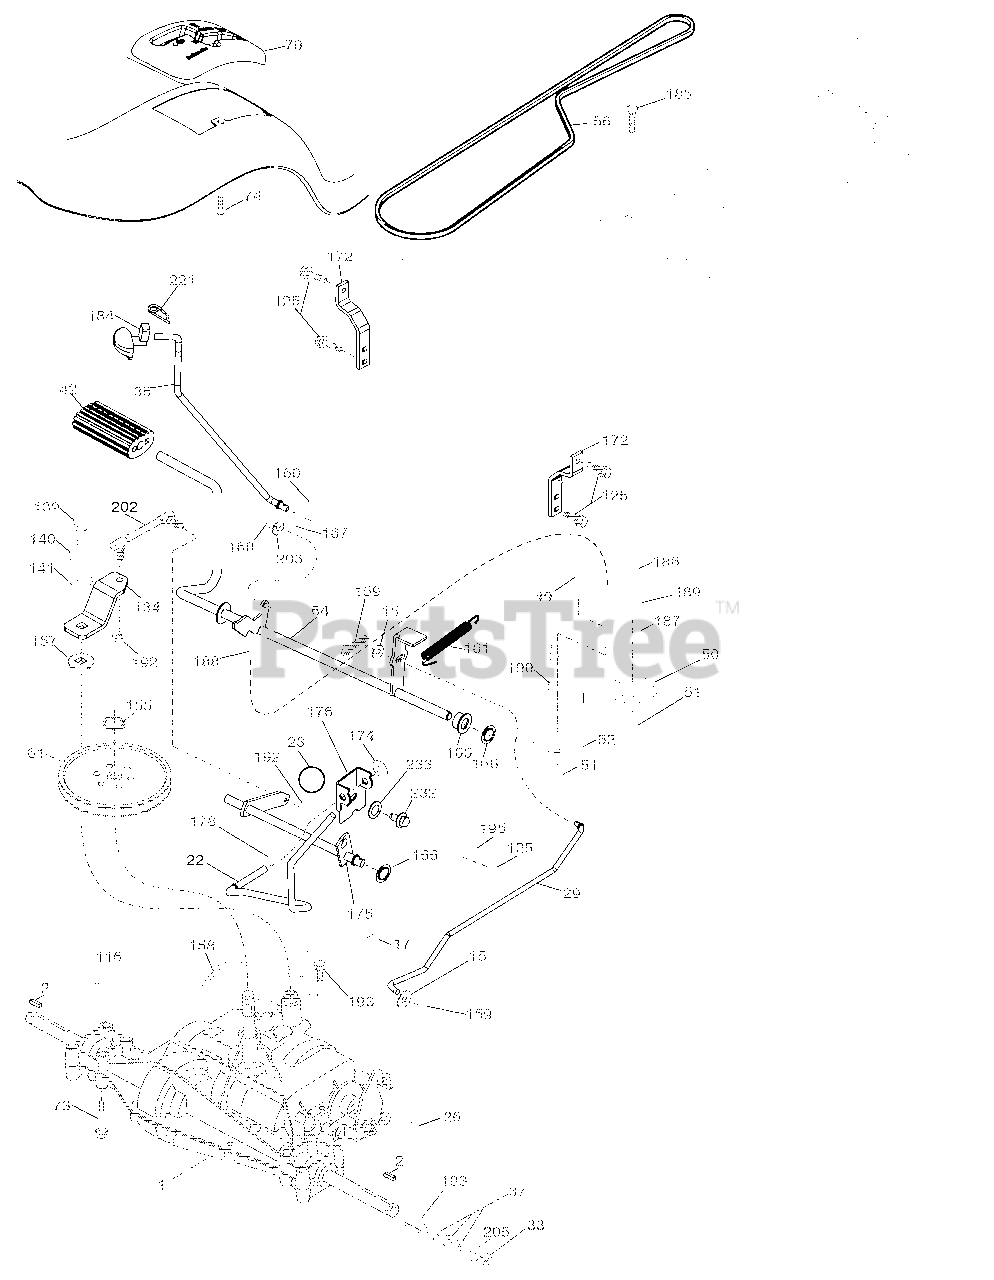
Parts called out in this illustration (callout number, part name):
1	TRANSAXLE, PEERLESS 206-565 (197941)(ORDER PARTS FROM TRANSAXLE MANUFACTURER.)
2	KEY 1/4 X 2.5
15	WASHER.13/32 X 13/16 X 16 GA.
17	SPRING.BRAKE.PEERLESS/D6800.TX
22	ROD.SHIFT.FENDER.TLT.2006
26	SPRING.BRAKE.RTN.GR DR.TEX.006
29	ROD.BRAKE.PEERLESS/D6800
33	E-RING.#5133-75
35	ROD, BRAKE, PARK
37	COVER PEDAL BLK ROUND
42	COVER PEDAL BLK ROUND
49	BOLT.RDHD.3/8-16UNCX1-3/4.GR5
50	IDLER.FLAT.910"OFFSET
51	Nut, Hex, Flangelock 3/8-16
52	IDLER.V-GROOVE.910"OFFSET
56	V-BELT.DRV.97.40"PMST/DANA
61	PULLEY.TRANSAXLE.18/20"TIRES
64	SHAFT ASM.PEDAL.BRAKE CONTROL
70	CONSOLE SHIFT
73	BOLT 5/16-18 X 2 1/2 G.5
74	SCREW.HEX.WSH.HI-LO.1/4X1/2UNC
116	Nut, Lock Hex Flange 5/16-18 u
125	SCREW.5/16-18X3/4.SMGML.TAP/BL
134	ASM SHIFT
139	BOLT.1/4-28 UNF.GR8.W/PATCH
140	Washer, Lock 1/4
141	WASHER.9/32 X 3/4 X 10 GA.
155	Ring, Retainer
157	WASHER.PLATE.SHF..388 SQ.HOLE
158	KEEPER.T/A.PMS/D4360/D680.1820
159	PIN.COTTER.1/8 X 3/4.CAD.
160	RETAINER.CLIP(M).DIA.290
161	SPRING.RETURN.CLUTCH.6.75
165	BUSHING.SHAFT.BRAKE.HAND CONTR
166	NUT PUSH .625
167	LATCH.BRAKE.PARKING
172	STRAP.TRQ.LH.GEAR DRIVE.LT.TEX
174	NUT.PUSH..500
175	SHAFT ASM. SHIFT GEAR DRIVE
176	ARM.CLEVIS.ROD.SHIFT
178	SPRING.SHIFT.GT.2006
183	SPACER.AXLE.HYDRO/PEERLES
184	HANDLE PARKING BRAKE
185	BOLT.RDHD.3/8-16UNC X2-3/4 GR5
186	SPACER.RETAINER
187	WASHER.13/32 X 2 X 10 GA.
188	LINK.CLUTCH.GROUND DRIVE
189	BELLCRANK.GROUNDRIVE.NSTG/NSTL
190	KEEPER.BELLCRANK.DRIVE.GROUND
192	NUT.LOCK.CENTER.1/4-28 FNTHD.
193	SCREW.5/16-18X3/4.SMGML.TAP/R
195	BRACKET.ROD.BRK.PEERLESS/D6800
203	Washer 11/32 x 11/16 x 16 Ga.
205	WASHER.25/32 X 1-5/8 X 16GA.
221	RETAINER.SPRING.CLIP.HANDLE
232	BOLT.FIN HEX.7/16-14X1 GR5
233	WASHER.SERRATED
